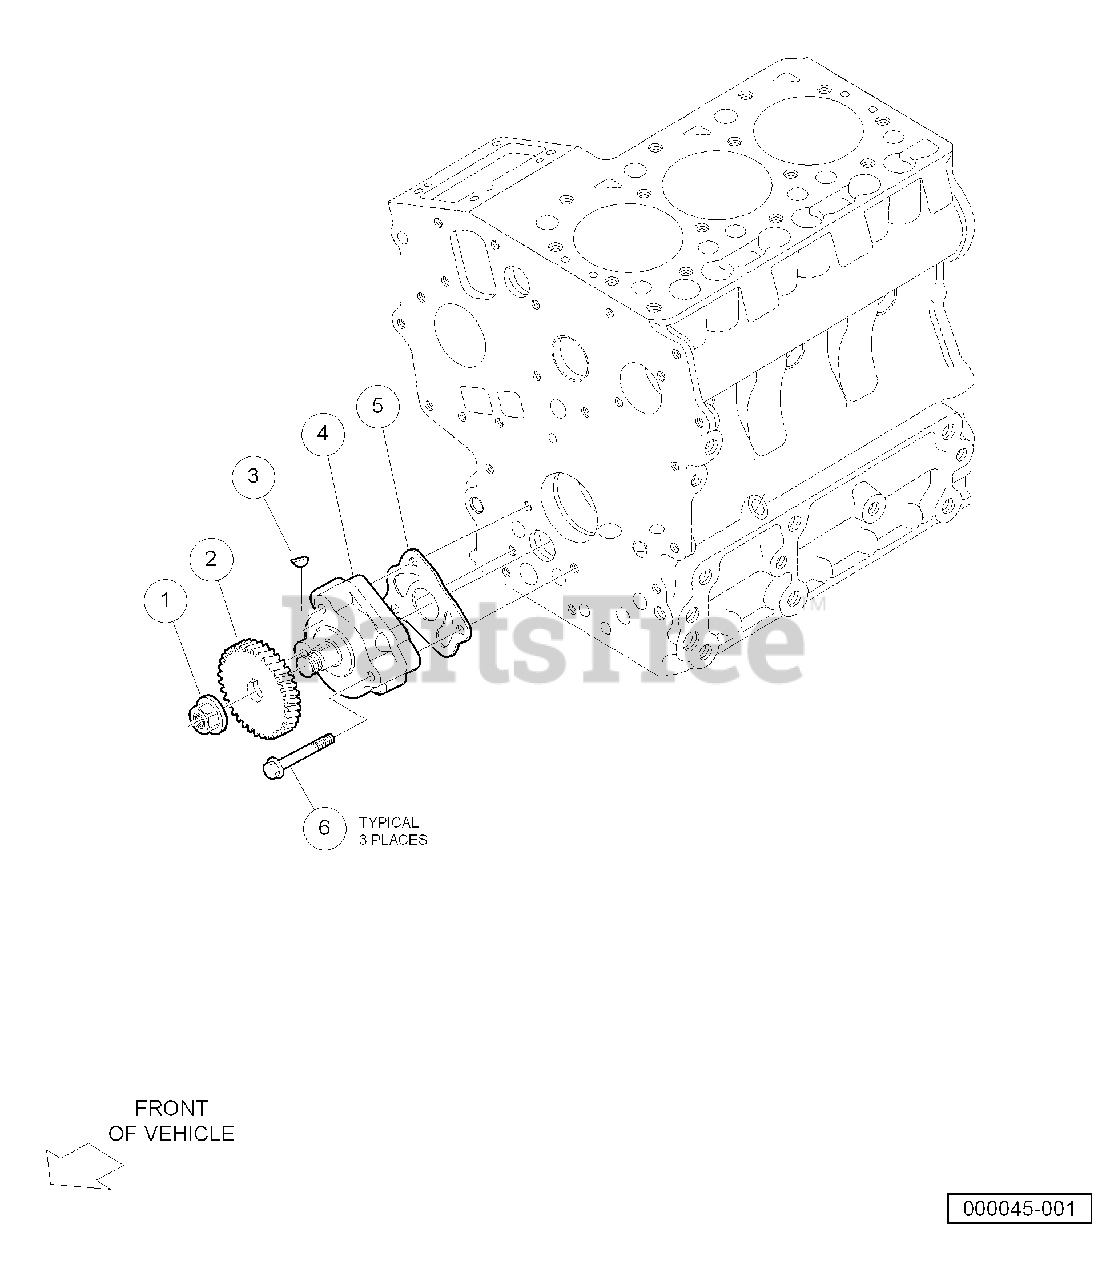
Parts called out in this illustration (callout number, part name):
1	Nut, Flange, D722 Oil Pump
2	Gear, Oil Pump Drive
3	Key, Feather, 8x4
4	Assy, Pump, Oil
5	Gasket, Oil Pump
6	Bolt, Oil Pump
